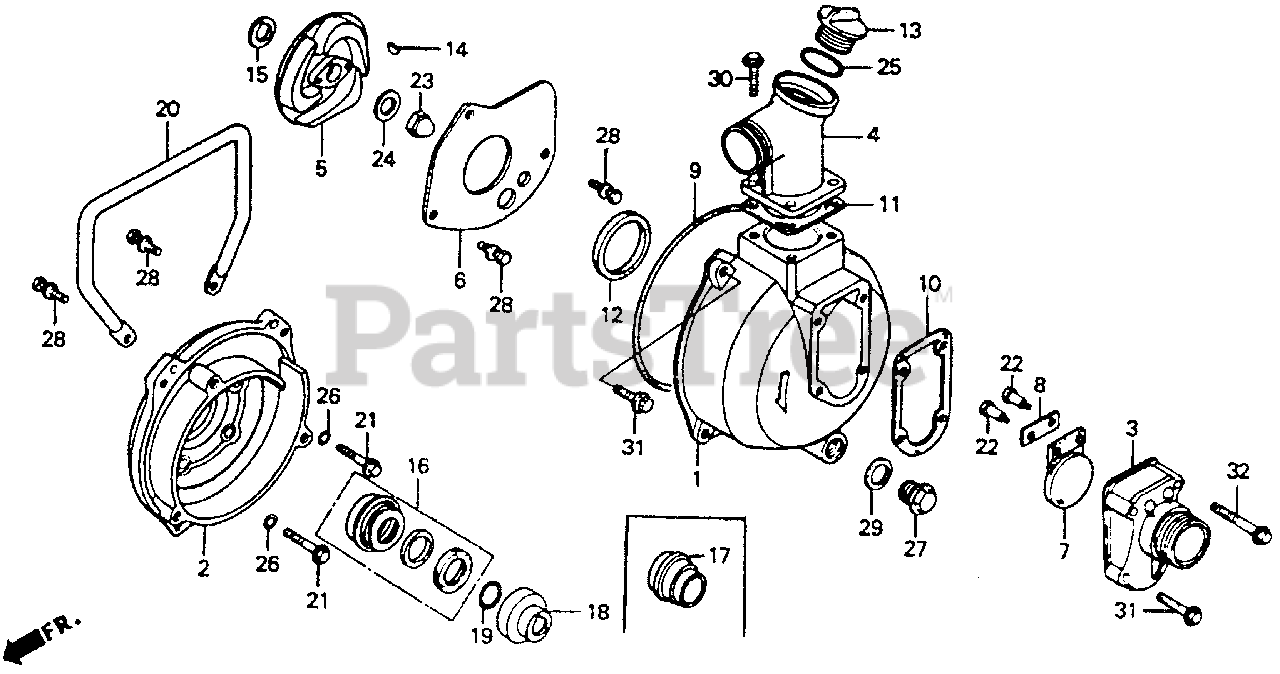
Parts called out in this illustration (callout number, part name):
2	COVER, CASE *NH2M* (METALLIC SILVER)
3	PIPE PUMP, IN.
4	PIPE, PUMP OUTLET
6	DISK, FRICTION
7	VALVE, IN.
8	RETAINER, VALVE
9	RING, CASING SEAL
10	GASKET, IN.
11	GASKET, OUTLET
12	RING, CENTER SEAL
13	CAP, FILLER
14	KEY, IMPELLER
15	SHIM, ADJUSTER
16	SEAL ASSY., MECHANICAL WATER
17	SEAL ASSY., MECHANICAL WATER
18	COLLAR, SEAL SETTING
19	O-RING, MECHANICAL SEAL
21	BOLT, PUMP SETTING
22	BOLT, CHOKE LEVER
23	NUT, IMPELLER
24	WASHER (13MM)
25	O-RING, FILLER CAP
26	O-RING (7.5MM)
27	BOLT, DRAIN PLUG (20MM)
28	BOLT-WASHER (8X20)
29	WASHER, DRAIN PLUG (20MM)
30	BOLT, FLANGE (8X25)
31	BOLT, FLANGE (8X35)
32	BOLT, FLANGE (8X50)
